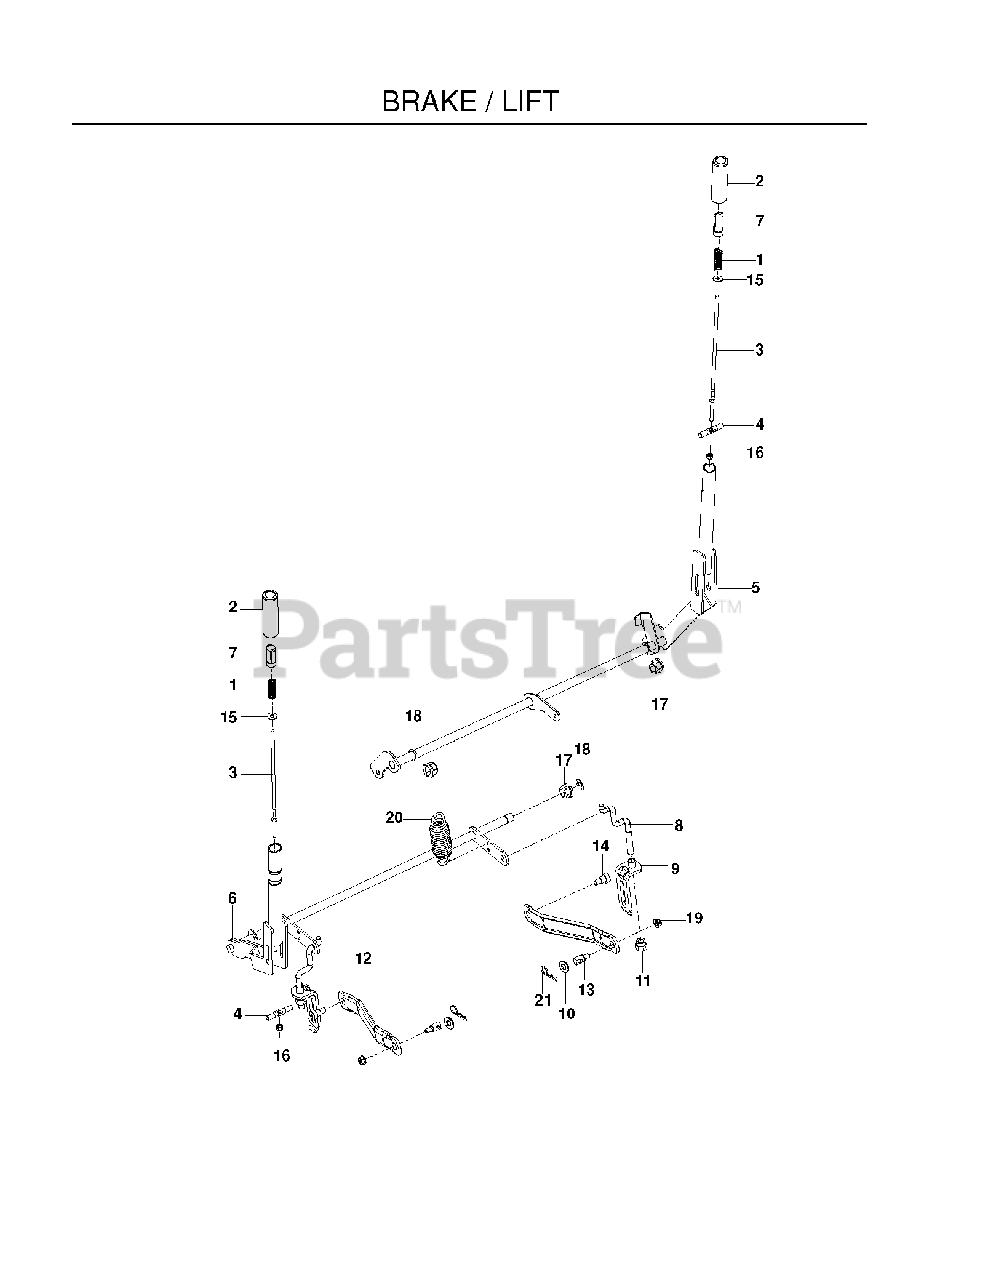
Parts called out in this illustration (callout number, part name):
1	SPRING, COMPRESSION
2	GRIP, HANDLE, BLACK
3	ROD, HANDLE RELEASE
4	ROD, LATCH RELEASE
5	SHAFT ASSY, BRAKE, MED, BLK
6	SHAFT.LIFT.MED.BLACK
7	BUTTON, PUSH, BLACK (2 2)
8	LINK, REAR SUSPENSION
9	ASSEMBLY, BRKT LINK
10	WASHER 5/8 FLAT
11	NUT, LIFT LINK 7/16-20
12	ARM.SUSPENSION.MOWER
13	STUD.FASTNER.W/ANTI-ROTATE
14	SB 3/8-16 X 3/8 SKT HD ZD
15	WASHER 1/4 FLAT
16	NUT 1/4-20 NYLOC
17	PLASTIC NUT
18	E-RING 5/8
19	5/16-18 NYLOC FLANGE NUT
20	SPRING
21	HAIRPIN #4
